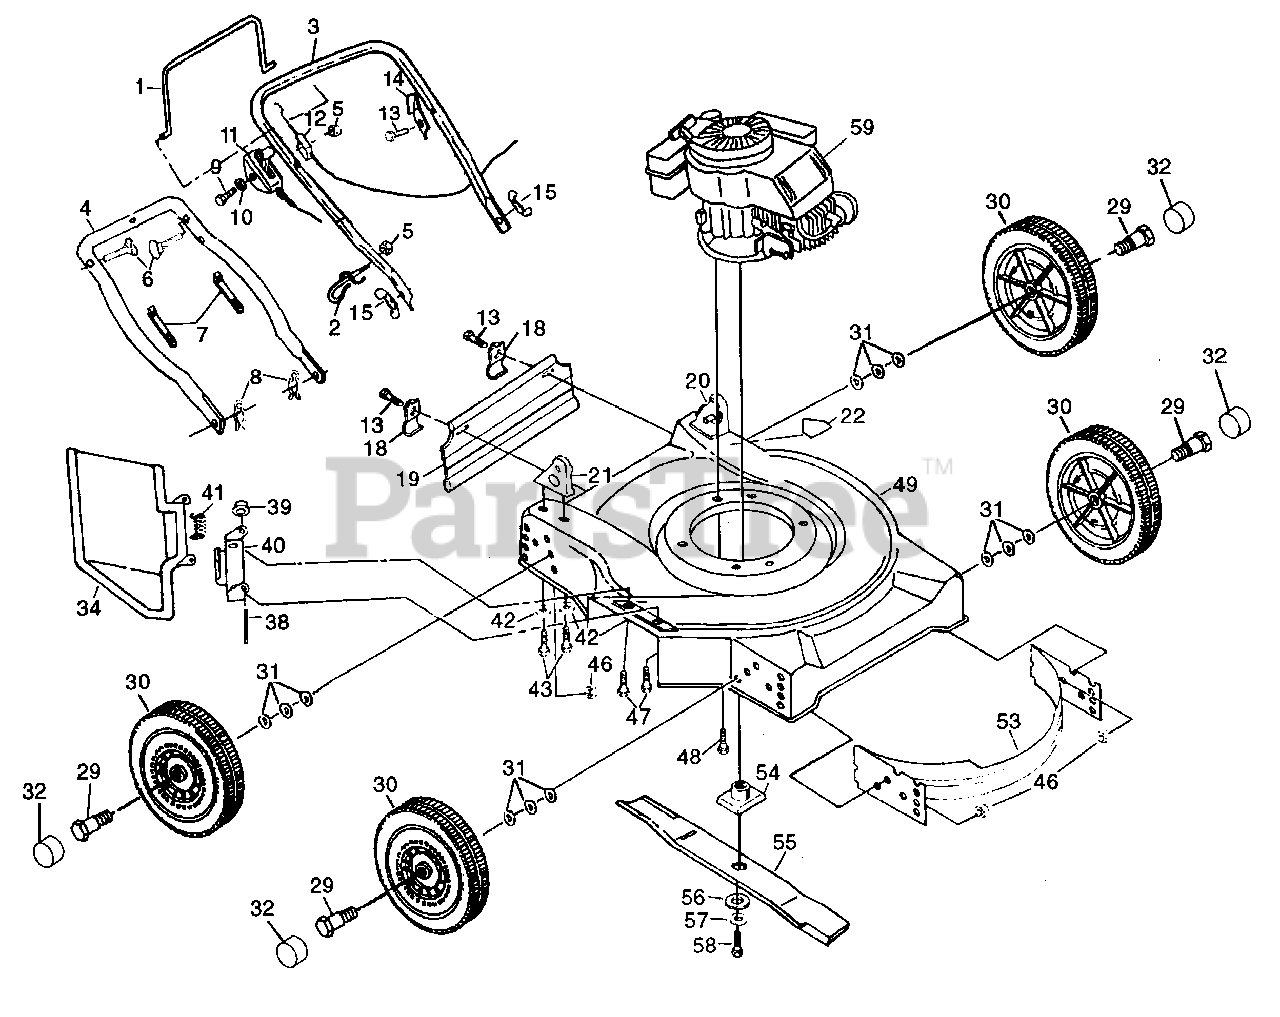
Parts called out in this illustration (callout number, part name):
1	Control Bar (AYP part number)
2	Rope Guide
3	Upper Handle (AYP part number)
4	Lower Handle (AYP part number)
5	Locknut 1/4-20 (AYP part number)
6	Handle Bolt (AYP part number)
7	Wire Tie (AYP part number)
8	Hairpin Cotter (AYP part number)
9	Machine Screw 1/4-20 x 2-1/8 (AYP part number)
10	Washer (AYP part number)
11	Throttle Control
12	Engine Zone Control Cable
13	Hex Washer Head Screw #10-24 x 1/2 (AYP part number)
14	Up-Stop Bracket (AYP part number)
15	Wing Nut (AYP part number)
18	Rear Deflector Bracket (AYP part number)
19	Rear Deflector
20	Handle Bracket Assembly (Left) (AYP part number)
21	Handle Bracket Assembly (Right) (AYP part number)
22	Danger Decal (AYP part number)
29	Shoulder Bolt (AYP part number)
30	Wheel Assembly (AYP part number)
31	Washer (AYP part number)
32	Hub Cap (AYP part number)
34	Discharge Guard
38	Hinge Rod (AYP part number)
39	Speed nut (AYP part number)
40	Housing Bracket (AYP part number)
41	Torsion Spring (AYP part number)
42	Flat Washer (AYP part number)
43	Screw 5/16-18 x 3/4 (AYP part number)
46	Locknut 3/8-16 (AYP part number)
47	Hex Head Thread Rolling Screw w/Sems 1/4-20 (AYP part number)
48	Hex Head Thread Rolling Screw 3/8-16 x 1-1/8 (AYP part number)
49	Lawn Mower Housing
53	Front Baffle (AYP part number)
54	Blade Adapter (AYP part number)
55	20" Blade
56	Hardened Washer (AYP part number)
57	Helical Lockwasher 3/8 (AYP part number)
58	Hex Head Screw 3/8-24 x 1-3/8 Grade 8
